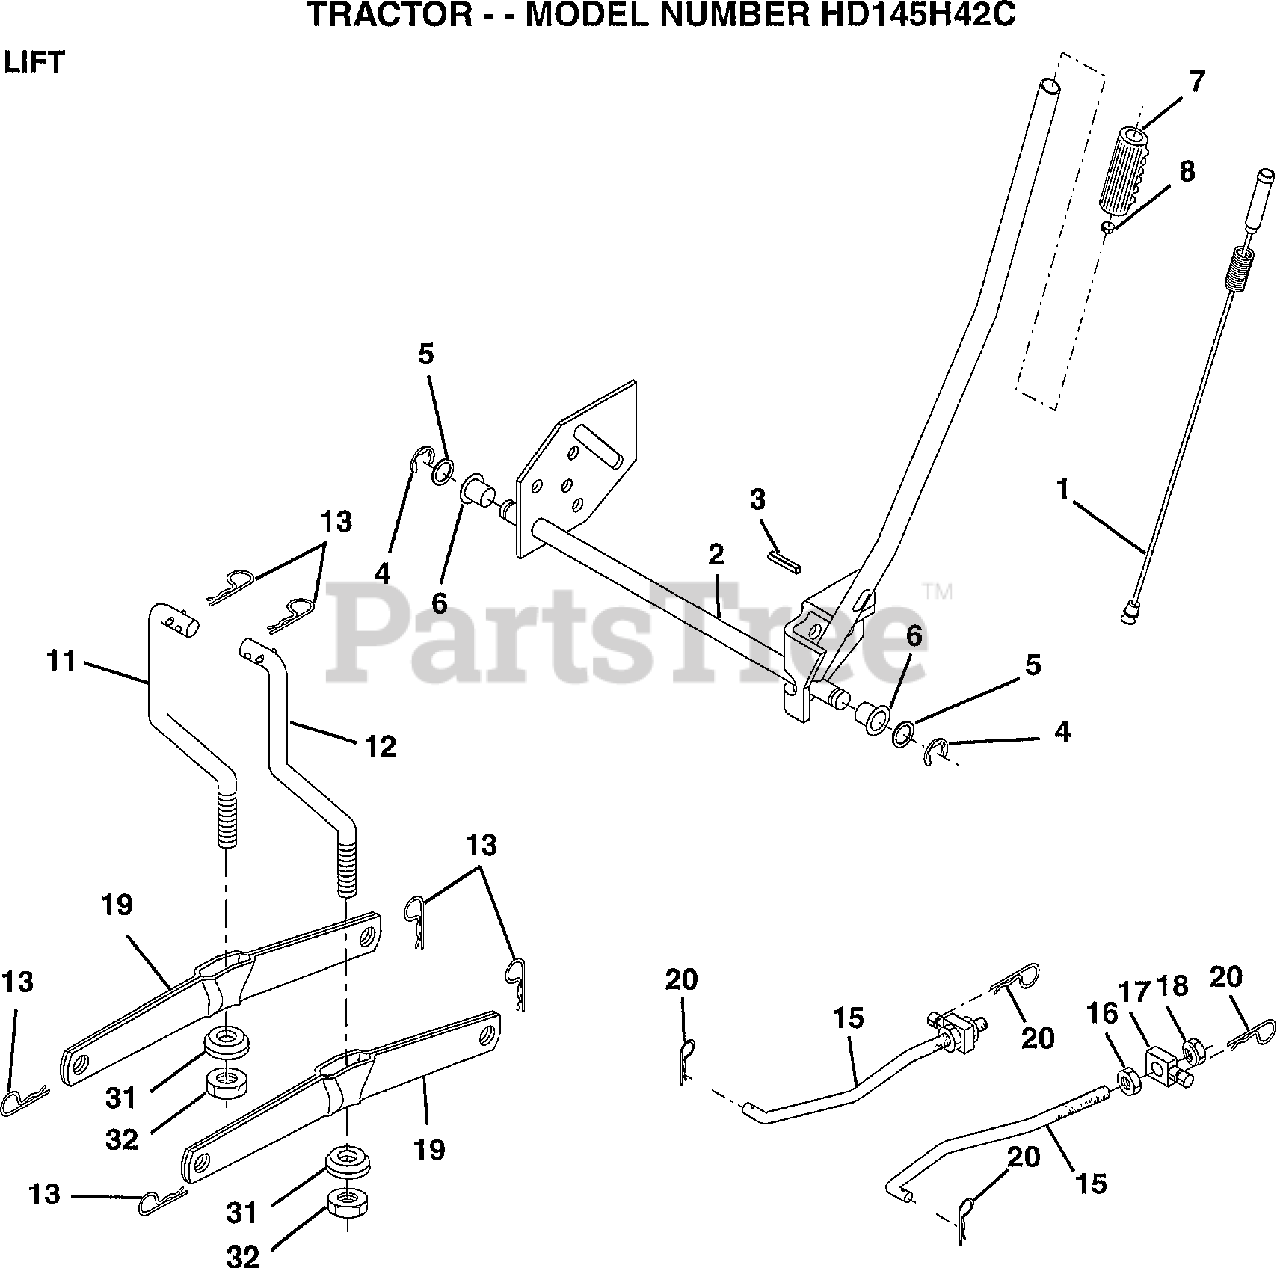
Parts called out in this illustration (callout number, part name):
1	WIRE ASM W.SPRING
2	"SHAFT ASM LIFT,RH"
3	PIN-GROOVE LT
5	WASHER
6	NYLON BEARING
7	GRIP
15	LINK.FRONT
16	NUT
17	TRUNION
18	NUT.LK.W/WSH.1/2.
19	ARM SUSP REAR
20	RETAINER.SPRING
31	BEARING PVT LH
32	NUT.CROWNLOCK.3/8
